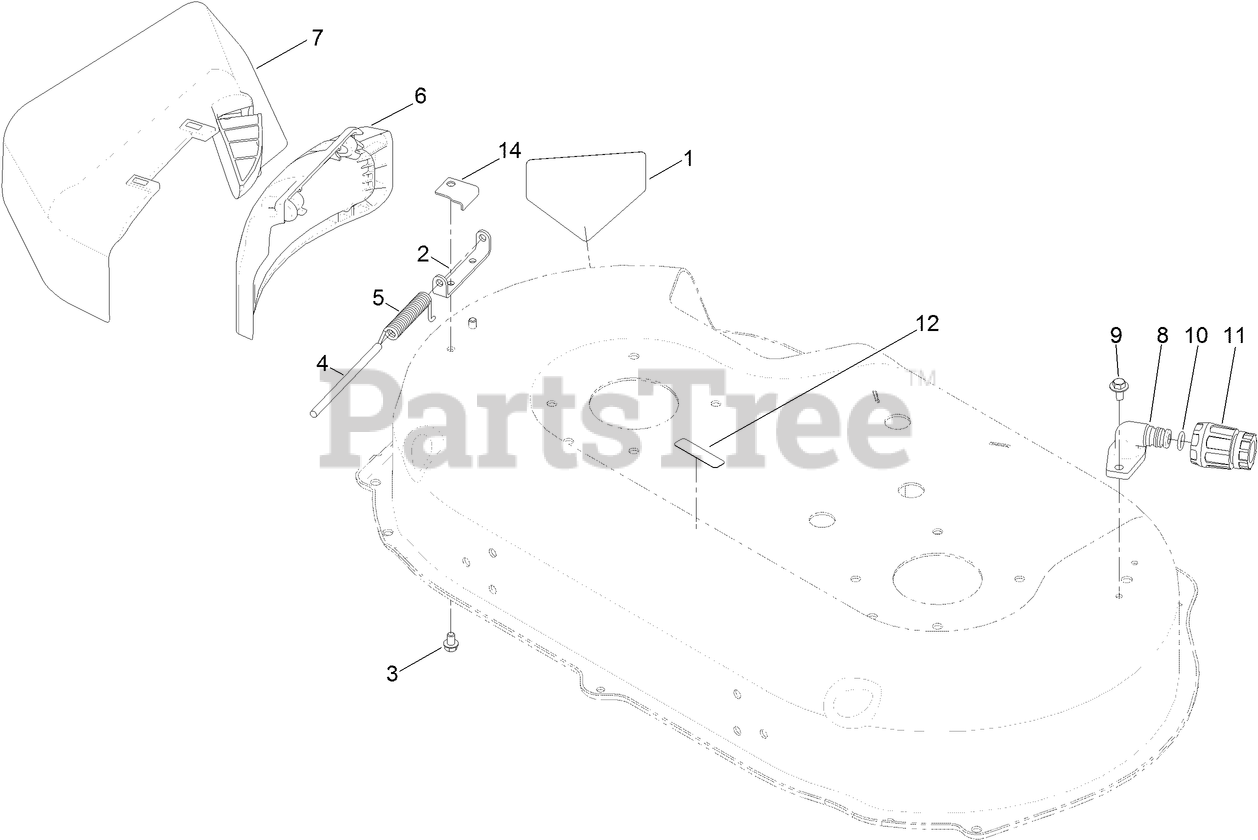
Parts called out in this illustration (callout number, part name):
1	DECAL-DANGER
2	BRACKET-COVER
3	SCREW-HWH
5	SPRING-TORSION, COVER
7	SIDE DISCHARGE CHUTE ASM
9	SCREW-HHFTF
10	O-RING
11	CONNECTOR-HOSE
12	DECAL-WARNING
14	PLATE-SPRING
